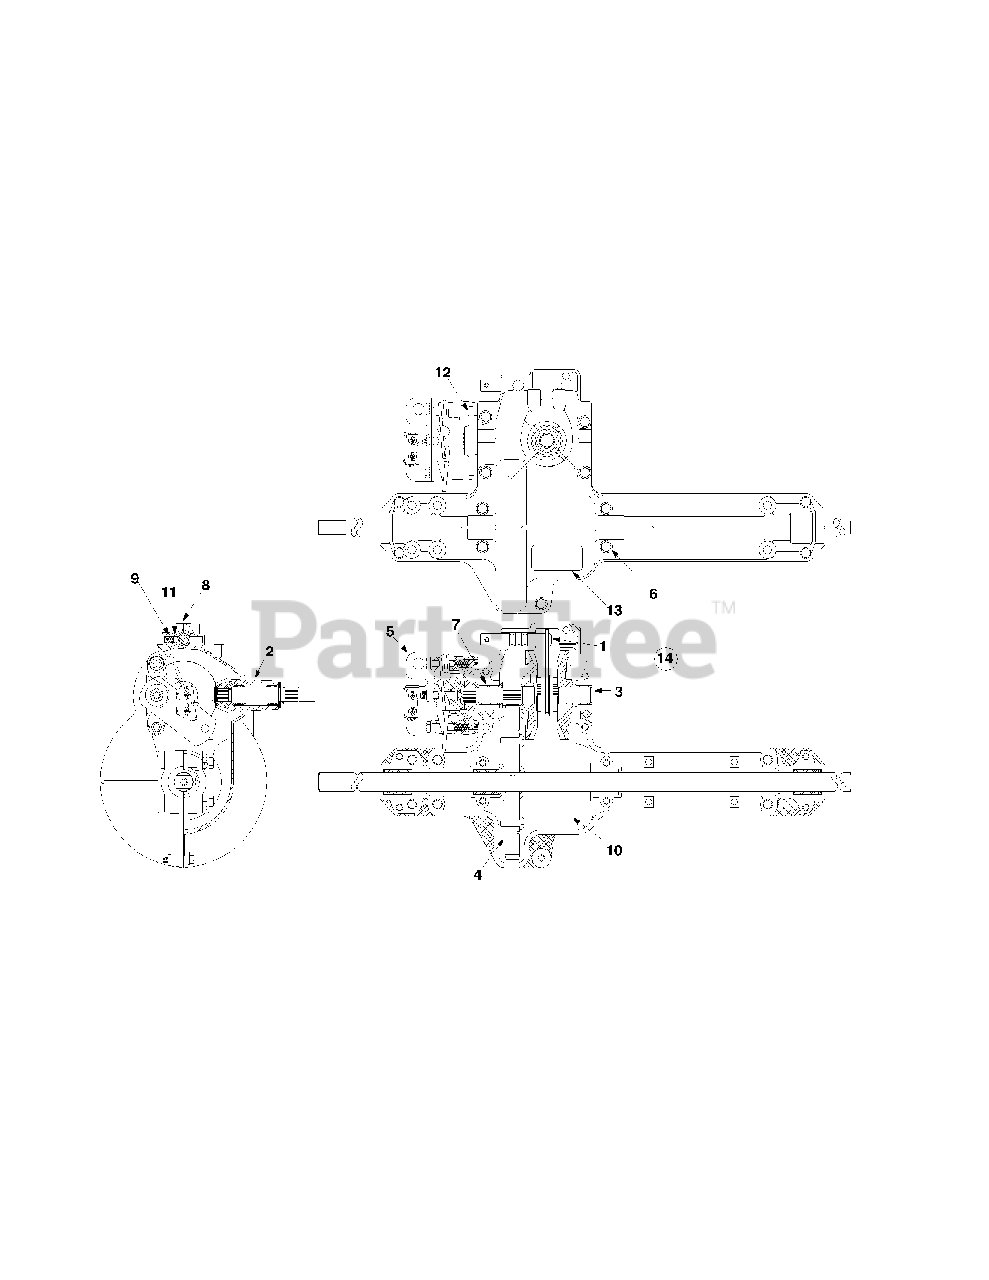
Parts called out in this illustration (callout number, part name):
1	Shaft Assembly: Detent
2	Upper Housing Assembly
3	Drive Shaft Assembly: LH Brake
4	Axle Assembly
5	Brake Assembly: Yoke LH
6	TT Screw 1/4-20 x 1.625"
7	Brake Pad
8	Lower Housing
9	Spring Detent
10	Grease
11	Ball: Detent: .250
12	Brake Disc
13	Label
14	Transmission Assembly Complete
